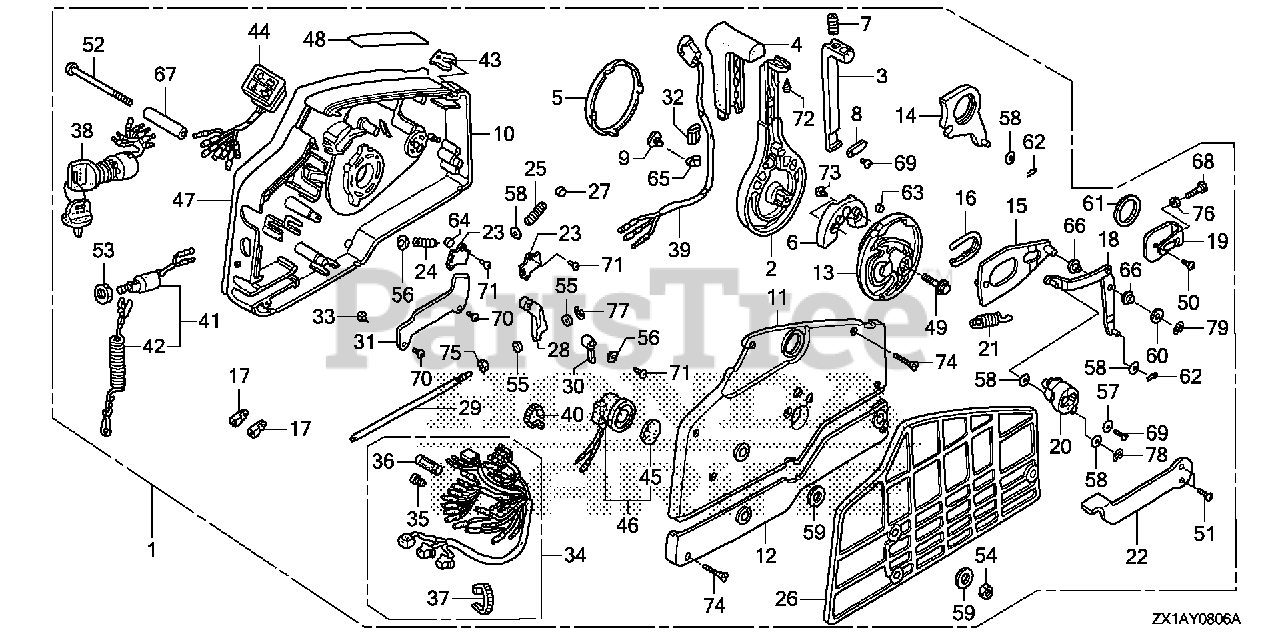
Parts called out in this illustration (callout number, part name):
1	BOX ASSY., REMOTE CONTROL (NHK MEC)
1	BOX ASSY., REMOTE CONTROL (TROLLING CONTROL)(NHK MEC)
2	HANDLE, REMOTE CONTROL
3	LEVER, HANDLE LOCK
4	GRIP, REMOTE CONTROL HANDLE
5	CAP, HANDLE
6	BLOCK, NEUTRAL LOCK
7	SPRING, REMOTE CONTROL HANDLE
8	PLATE, LEVER SETTING
9	CLAMP, HARNESS
10	HOUSING, REMOTE CONTROL BOX (A)
11	HOUSING, REMOTE CONTROL BOX (B)
12	HOUSING, REMOTE CONTROL BOX (C )
13	WHEEL, CONTROL
14	ARM, SHIFT LINK
15	PLATE, SLIDING
16	COLLAR, SLIDING PLATE
17	PIVOT, SHIFT
18	ARM, LINK JOINT
19	BRACKET, LINK JOINT
20	WHEEL, ACCELERATOR
21	SPRING, ACCELERATOR WHEEL
22	LEVER, IDLE
23	PLATE, SPRING SETTING
24	SPRING, SHIFT CLICK
25	SPRING, CHOKE RETURN
26	SPACER, REMOTE CONTROL BOX
27	SPACER, CLICK SPRING
28	BLOCK, THROTTLE FRICTION
29	BOLT, FRICTION
30	SPACER, NEUTRAL SWITCH
31	CLAMP, POWER TILT CORD
32	PIPE, HARNESS GUIDE
33	SPACER, CABLE CLAMP
34	CABLE ASSY., REMOTE CONTROL (B) (FOR 4-LED)
35	PLUG, CONNECTOR (INNER) (TROLLING CONTROL)
36	PLUG, CONNECTOR (OUTER) (ENGINE NO.)
37	TIE, CABLE (NATURAL 2.4X92) Use up to Frame SN 1300359.
38	SWITCH ASSY., COMBINATION (SINGLE) (DUAL)
39	SWITCH ASSY., POWER TRIM-TILT
40	BAND (BLACK 3.5X140)
41	SWITCH ASSY., EMERGENCY STOP
42	WIRE, EMERGENCY (SINGLE) (DUAL)
43	CLIP, EMERGENCY LOCK
44	LAMP ASSY., INDICATION
45	PLATE, TURN SIGNAL BUZZER DUAL QTY = (2) (SINGLE)
46	BUZZER, WARNING DUAL QTY = (2) (SINGLE)
47	PLATE, REMOTE CONTROL (COUTION COLOR=RED & YELLOW)
48	MARK, FAST IDLE
49	BOLT, FLANGE (8X35) Use from Frame SN 4800713.
50	SCREW, PAN (6X10)
51	SCREW, FLAT (5X12) Use from Frame SN 4800713.
52	SCREW (6X95)
53	NUT, HEX. (16MM) DUAL QTY = (2) (SINGLE)
54	NUT, HEX. (6MM)
55	WASHER, PLAIN (4MM) Use from Frame SN 4800713.
56	WASHER, PLAIN (5MM)
57	WASHER, PLAIN (5MM)
58	WASHER, PLAIN (6MM) Use from Frame SN 4800713.
59	WASHER (6MM)
60	WASHER, PLAIN (8MM) Use from Frame SN 4800713.
61	WASHER (28MM)
62	PIN, LOCK (6MM)
63	PIN (6X6)
64	ROLLER, CLICK
65	CLIP, WIRE HARNESS (6.3MM)
66	COLLAR, LINK JOINT
67	COLLAR, DISTANCE (6X10X43.5)
68	BOLT, HEX. (5X16)
69	SCREW, PAN (5X10)
70	SCREW, TAPPING (5X8) (FOR SILVER MUFFLER)
71	SCREW, TAPPING (5X10)
72	SCREW, TAPPING (5X12)
73	SCREW, TAPPING (6X16)
74	SCREW, TAPPING (5X25)
75	NUT, HEX. (6MM)
76	NUT, HEX. (5MM)
77	E-RING (3MM)
78	E-RING (4MM)
79	E-RING (7MM)
